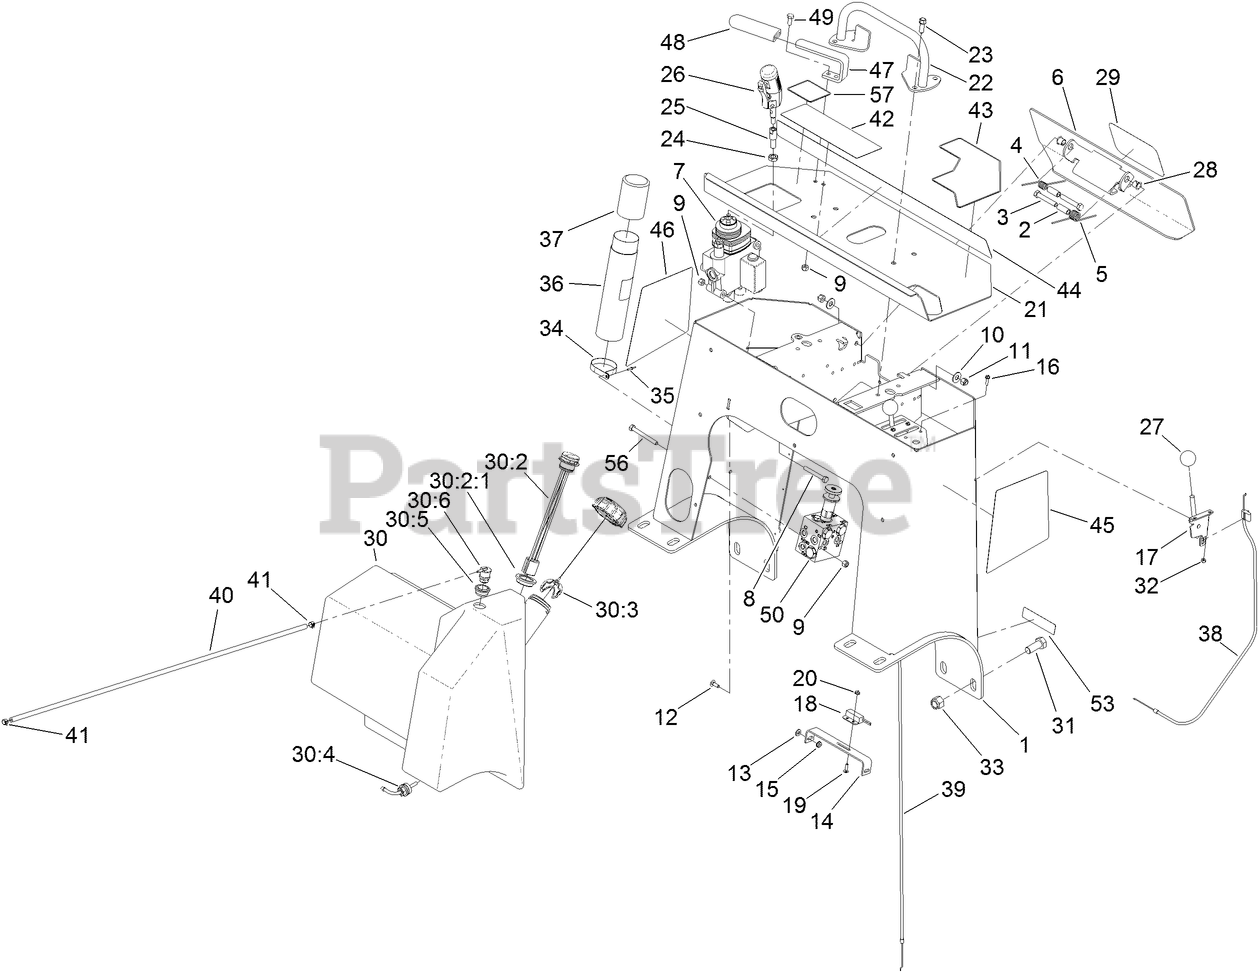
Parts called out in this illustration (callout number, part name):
2	SPACER-SPRING
3	SCREW-HH
4	SPRING-TORSION, LH
5	SPRING-TORSION, RH
6	PLATE-BACKUP
7	HYD VALVE ASM
8	SCREW-HH
9	NUT-LOCK, NI
10	WASHER-FLAT
11	NUT-LOCK, NI
12	BOLT-CARR
13	WASHER-FLAT
14	PLATE-SWITCH
15	NUT-KEPS
16	SCREW-HWH
17	LEVER-CONTROL
18	SWITCH-PROXIMITY
19	SCREW-CARR
20	NUT-KEPS
21	COVER-CONTROL
22	BAR-REFERENCE
23	SCREW-TAPTITE
25	ADAPTER-HANDLE
26	TWO BUTTON HANDLE GRIP ASM
28	BUSHING-NYLINER
30	FUEL TANK ASM
30:2	GUAGE-FUEL
30:3	CAP-FUEL
30:4	FITTING-FUEL, BULKHEAD
30:5	GROMMET
30:6	VALVE-ROLLOVER
31	SCREW-HH
32	NUT-LOCK, NI
33	NUT-LOCK, NI
34	CLAMP-R
35	RIVET-POP
36	TUBE-MANUAL
37	CAP-HOUSING
38	CABLE-CONTROL
39	CABLE-THROTTLE
40	HOSE-FUEL
41	CLAMP-HOSE
42	DECAL-WARNING
43	DECAL-CONSOLE, LH
44	DECAL-CONSOLE, RH
45	DECAL-LOGO, LH
46	DECAL-LOGO, RH
47	BAR-ARM REST
48	GRIP-LEVER
49	SCREW-HH
50	SWEEP MANIFOLD ASM
53	DECAL-ARRESTER, SPARK
56	SCREW-HH
57	DECAL-JOYSTICK
